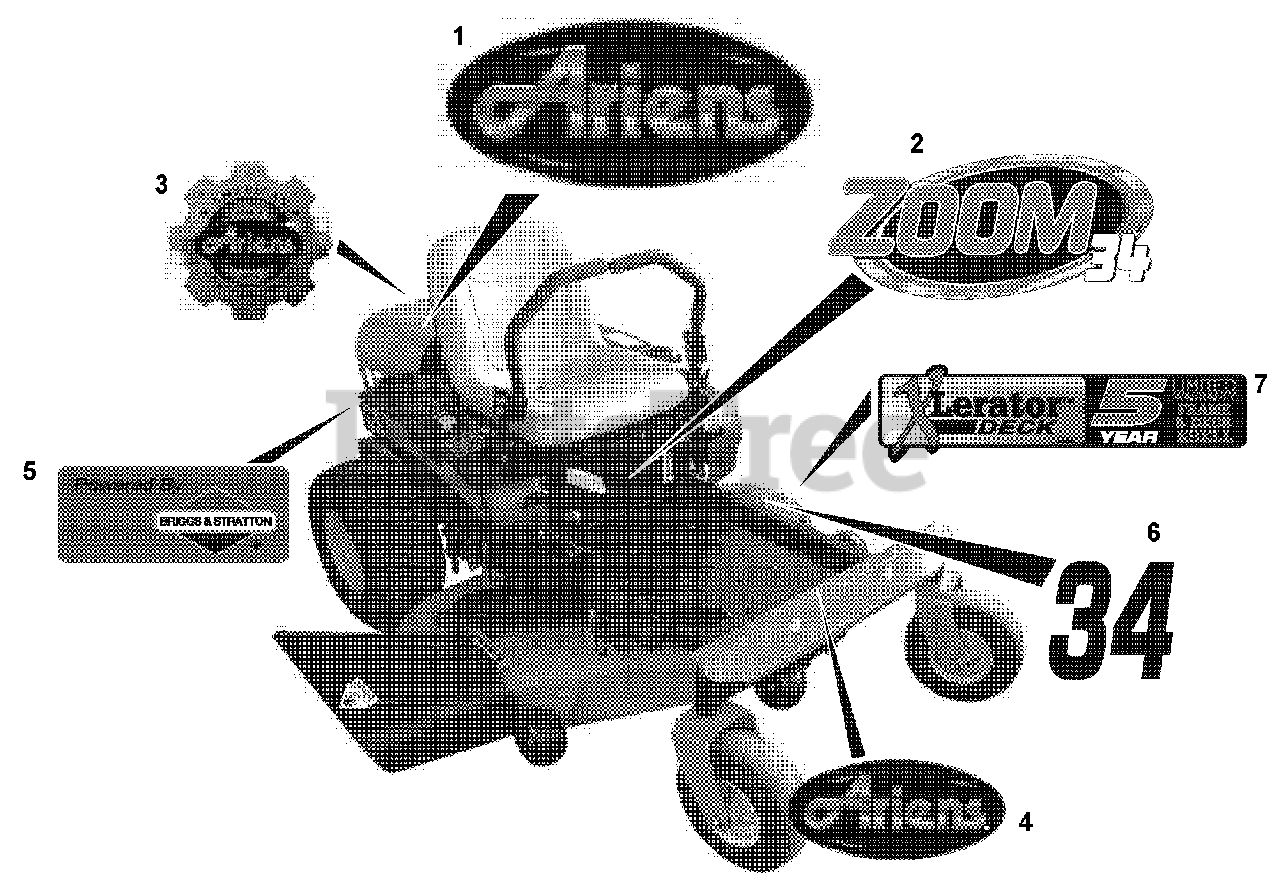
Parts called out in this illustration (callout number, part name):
1	DECAL, ARIENS JEWEL
2	DECAL, ZOOM 34
2	DECAL, ZOOM42
2	DECAL, ZOOM 50
3	DECAL, ARIENS HERITAGE-LARGE
4	DECAL, ARIENS JEWEL
5	DECAL, POWERED BY B&S
5	DECAL, POWERED BY KOHLER
6	DECAL, DECK SIZE, 34"
7	DECAL,DECK WARRANTY-XCEL ARIEN
